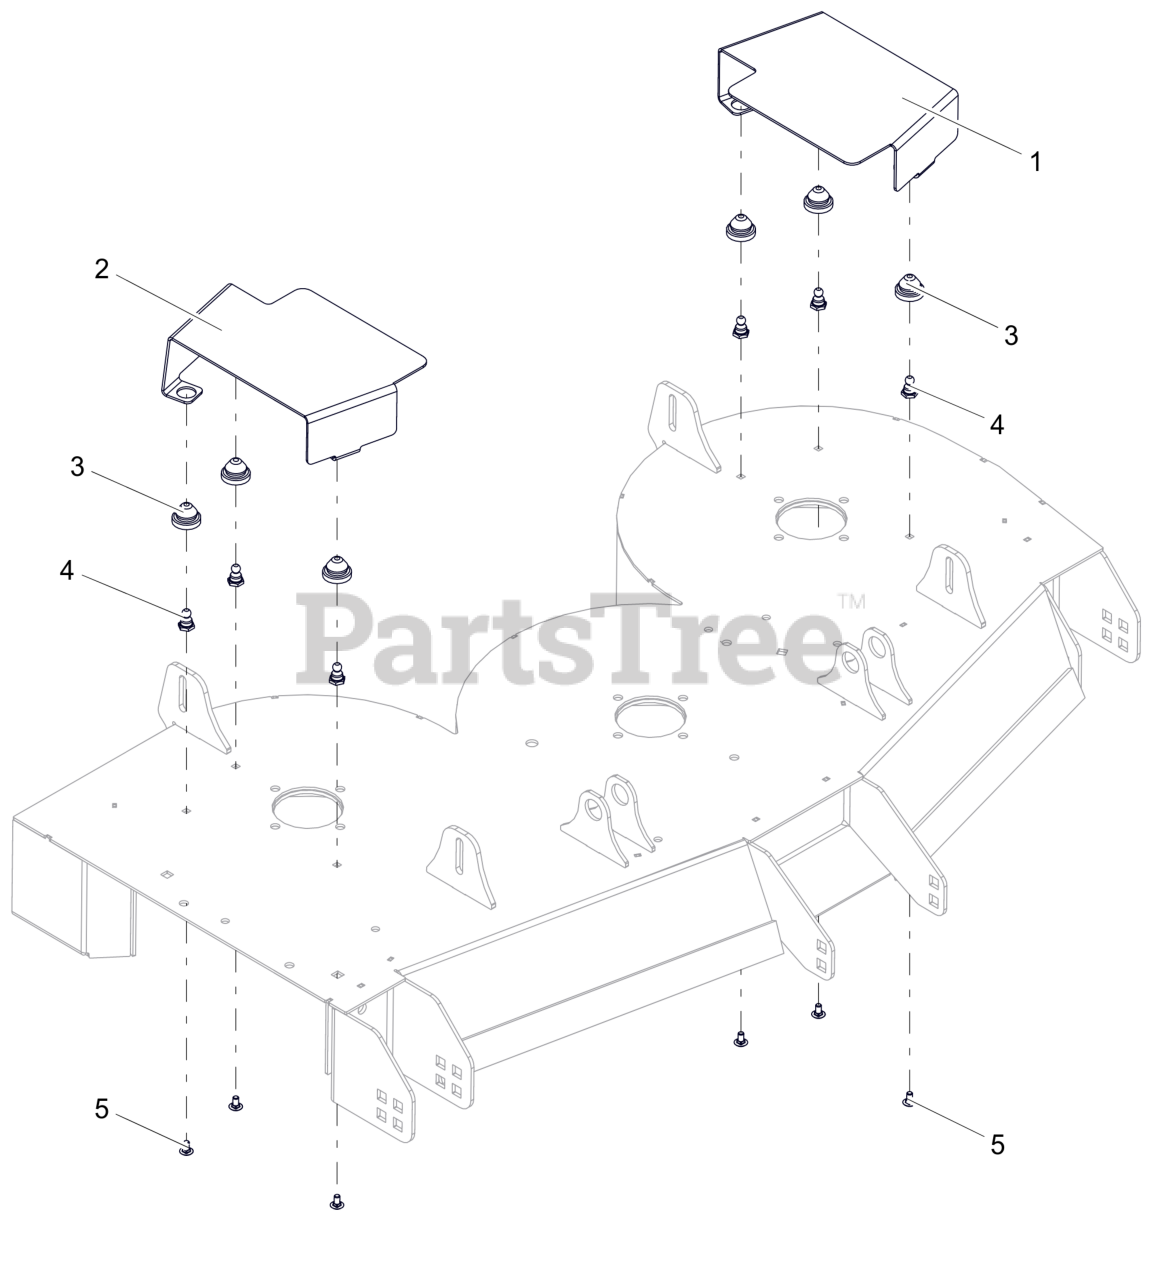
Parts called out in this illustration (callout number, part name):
1	GUARD-48-52" DECK LH BELT(RED)
2	GUARD-48-52" DECK RH BELT(RED)
3	COUPLING, RUBBER PUSH-IN
4	STUD, BALL FEMALE .250-20 THREAD
5	BLT, RHSSN.25-20X.500 G5 ZCC
